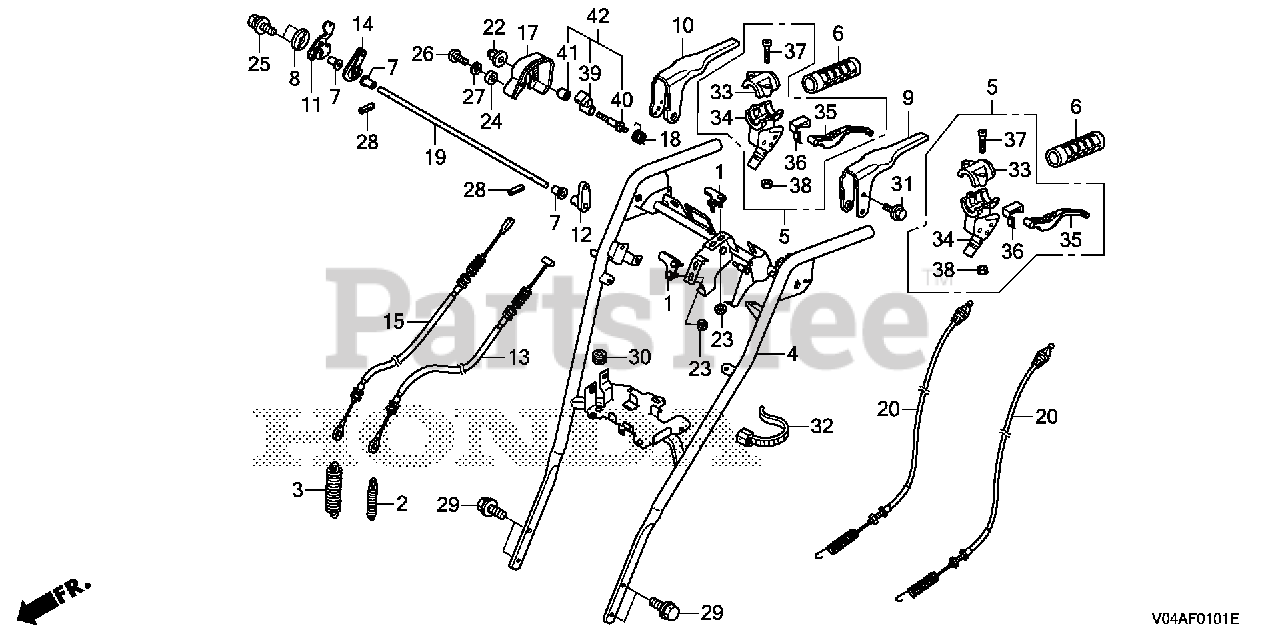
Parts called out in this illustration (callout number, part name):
1	BRACKET, STOPPER
2	SPRING, WHEEL TENSION
3	SPRING, AUGER TENSIONER
4	PIPE, HANDLE (UPPER) *NH105* (MAT BLACK)
5	LEVER ASSY., STEERING
6	GRIP, HANDLE
7	BUSHING (A)
8	BOSS, CLUTCH SPACER
9	LEVER, CLUTCH
10	LEVER, AUGER CLUTCH
11	BOSS, R. CLUTCH LEVER
12	BOSS, CLUTCH LEVER
13	CABLE, CLUTCH
14	BOSS, CAM LOCK
15	CABLE, AUGER CLUTCH
17	COVER, RATCHET
18	SPRING, RATCHET
19	SHAFT, CLUTCH LEVER
20	CABLE, STEERING
22	NUT, FLANGE CAP (6MM)
23	NUT, NYLON LOCK (6MM)
24	COLLAR, FUEL PETCOCK
25	BOLT-WASHER (6X16)
26	SCREW, PAN (4X12)
27	WASHER, PLAIN (4MM)
28	PIN, SPRING (4X20)
29	BOLT, FLANGE (8X16)
30	GROMMET, RESERVE TANK
31	BOLT, FLANGE (6X12) Use from Engine SN 2086984.
32	BAND, WIRE (165MM) (BLACK)
33	CLAMP (NA USE ALT:53175-V45-A01)
34	BRACKET (NA USE ALT:53175-V45-A01)
35	LEVER (NA USE ALT:53175-V45-A01)
36	PIVOT (NA USE ALT:53175-V45-A01)
37	BOLT, SOCKET (5X25) (NA USE ALT:53175-V45-A01)
38	NUT, NYLON LOCK (5MM) (NA USE ALT:53175-V45-A01)
39	RATCHET, LEVER
40	BOLT, RATCHET LEVER
41	COLLAR, RATCHET COVER
42	RATCHET KIT
